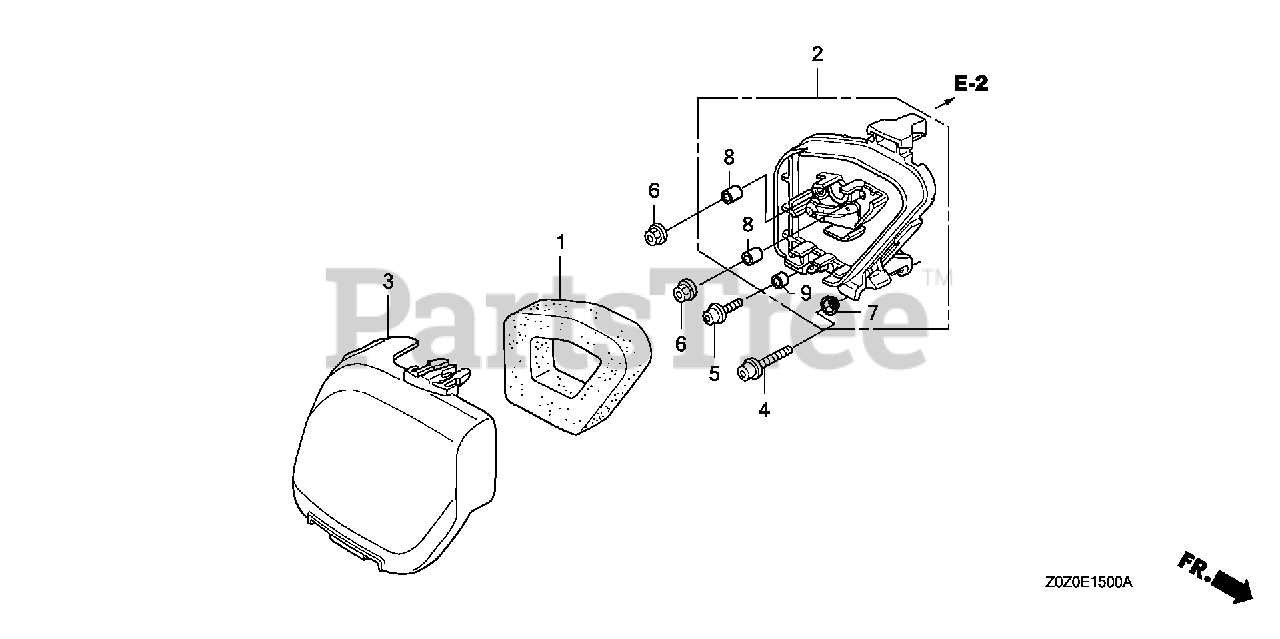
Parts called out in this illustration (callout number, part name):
1	ELEMENT, AIR CLEANER
2	HOUSING, AIR CLEANER
3	COVER, AIR CLEANER
4	BOLT, SOCKET (5X25)
5	BOLT, SOCKET (5X16)
6	NUT, FLANGE (5MM)
7	COLLAR, AIR CLEANER HOUSING
8	COLLAR, AIR CLEANER
9	COLLAR A, HEAD COVER
